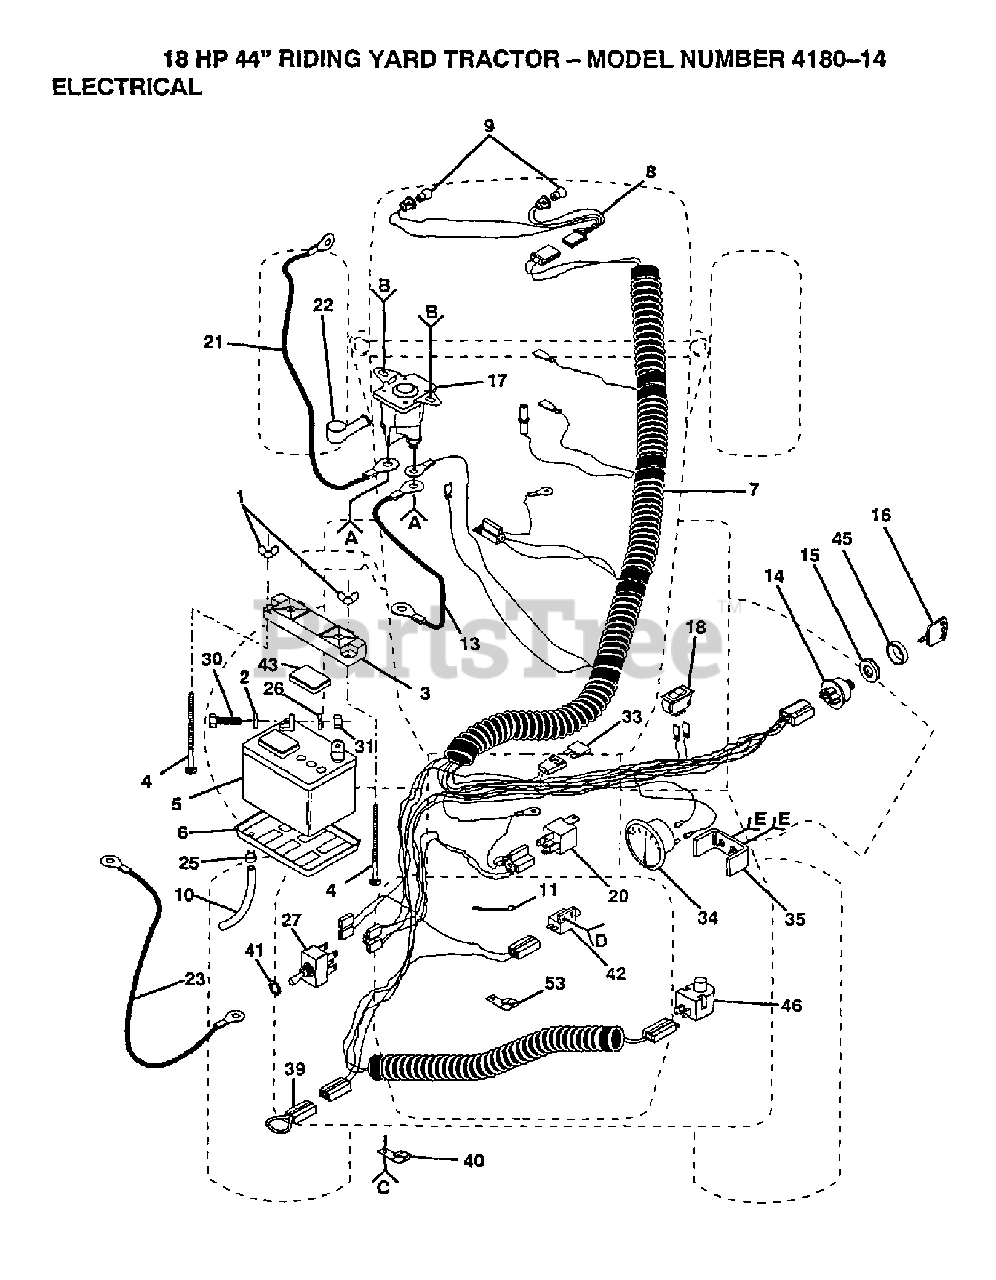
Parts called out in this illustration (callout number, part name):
1	WING NUT
2	WASHER
5	BATTERY
6	TRAY.BATTERY
7	R/B 6000 CENTER HUB ASSEMBLY
8	HARNESS LIGHT SOC
11	WIRE TIE
14	SWITCH YTV
15	NUT
16	KEY.MOLDED.GENERIC
17	SOLENOID KIT
18	SWITCH LT
20	FUSE HYT
21	BATTERY CABLE
22	Poulan TBD
23	TIRE HEAVY DUTY
25	HOSE CLAMP T
26	LOCKWASHER
30	BOLT.HEX.1/4.X.3/4.DICHROMATE
31	NUT
33	FUSE *
34	AMMETER.ROUND.15 AMP
39	LOOP-WIRE YTV
41	HEX NUT T (1 2)
42	SWITCH-INTER. GT
43	CAP BATTERY NLA
45	BEZEL.SWITCH.IGNITION
46	SWITCH SEAT
